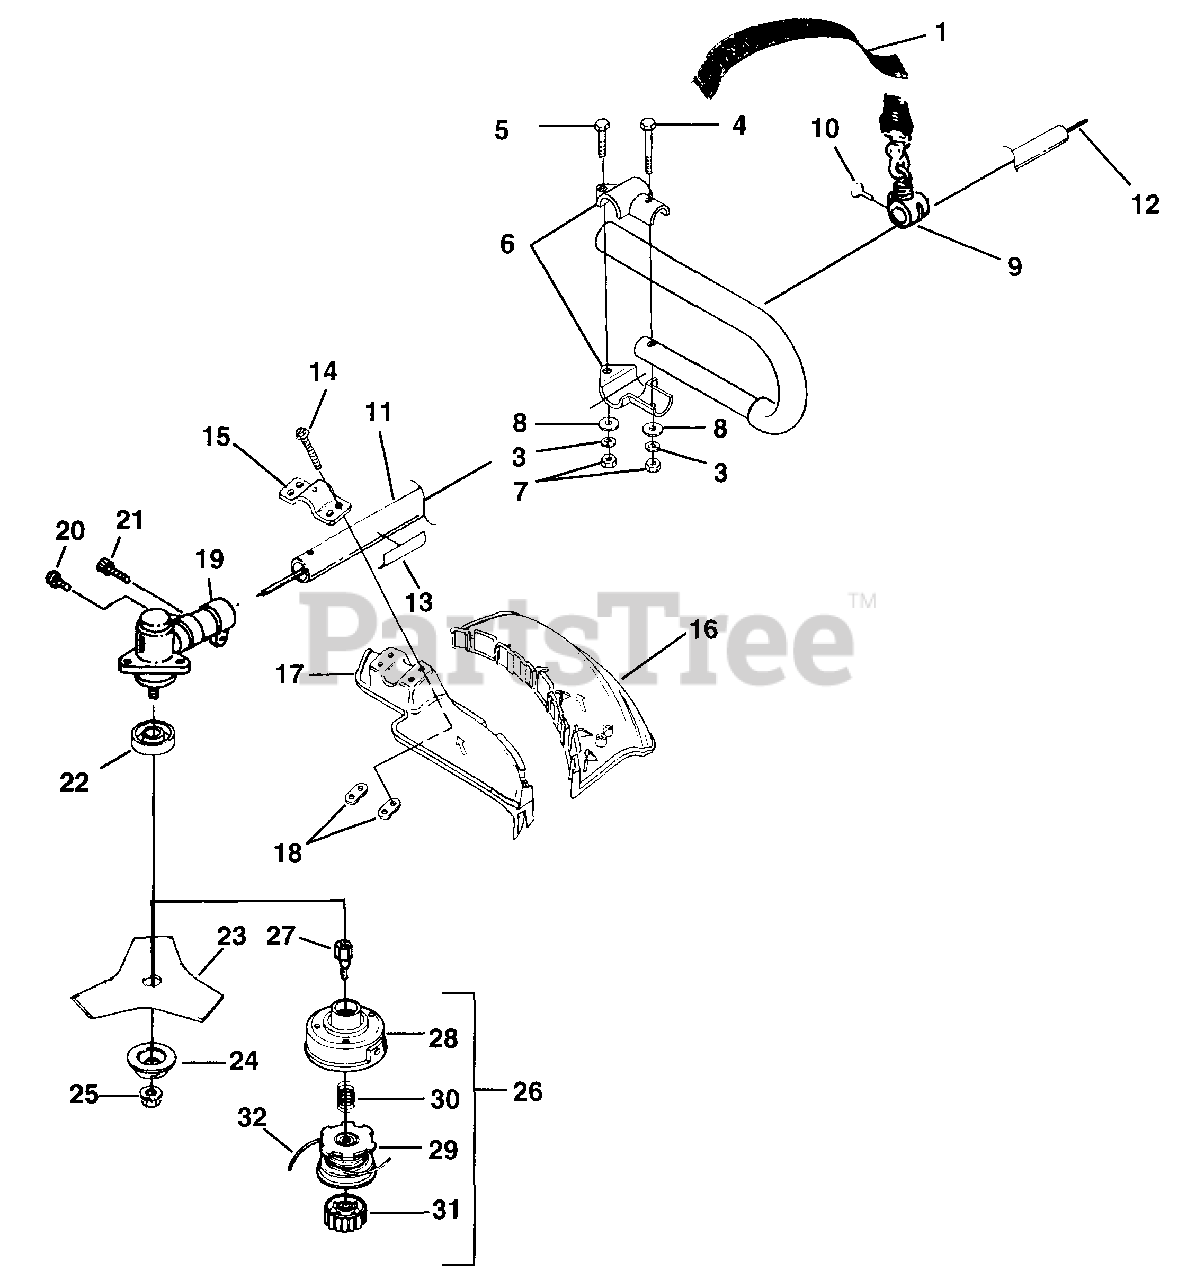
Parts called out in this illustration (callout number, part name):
1	HARNESS w/Connector
3	Washer-Lock
4	SCREW-Hex Hd. (1/4-20 X 1/2")
5	SCREW-Hex Hd. (1/4-20 X 1")
6	CLAMP-Handle Bar
7	NUT-Hex (1/4-20)
8	WASHER- Flat
9	BRACKET-Hanger
10	SCREW-Thumb (10-24 X 1/2")
11	HOUSING-Drive Shaft
12	SHAFT-Drive
13	DECAL-Warning
14	SCREW-Mach. Truss Hd. (10-24 X 3/4)
15	CLAMP
16	STRING SHIELD
17	BLADE GUARD
18	MOUNTING PLATE
19	GEAR HEAD
20	SCREW-Sems Hex Hd. (10-24 X 1/2")
21	SCREW-Cap Socket Hd. (1/4-20 x 7/8")
22	WASHER-Flange
23	BLADE-Tri-Arc
24	WASHER-Flange
25	NUT-Hex (L.H.)
26	STRINGHEAD COMPLETE
27	CONNECTOR-Drive
28	HOUSING & EYELET (Dual Line)
29	SPOOL & STRING (.095" Line)
30	SPRING-Compression
31	RETAINER-Spool (L.H.) (Red)
32	LINE-Replacement (.095" Dia.) (135')
